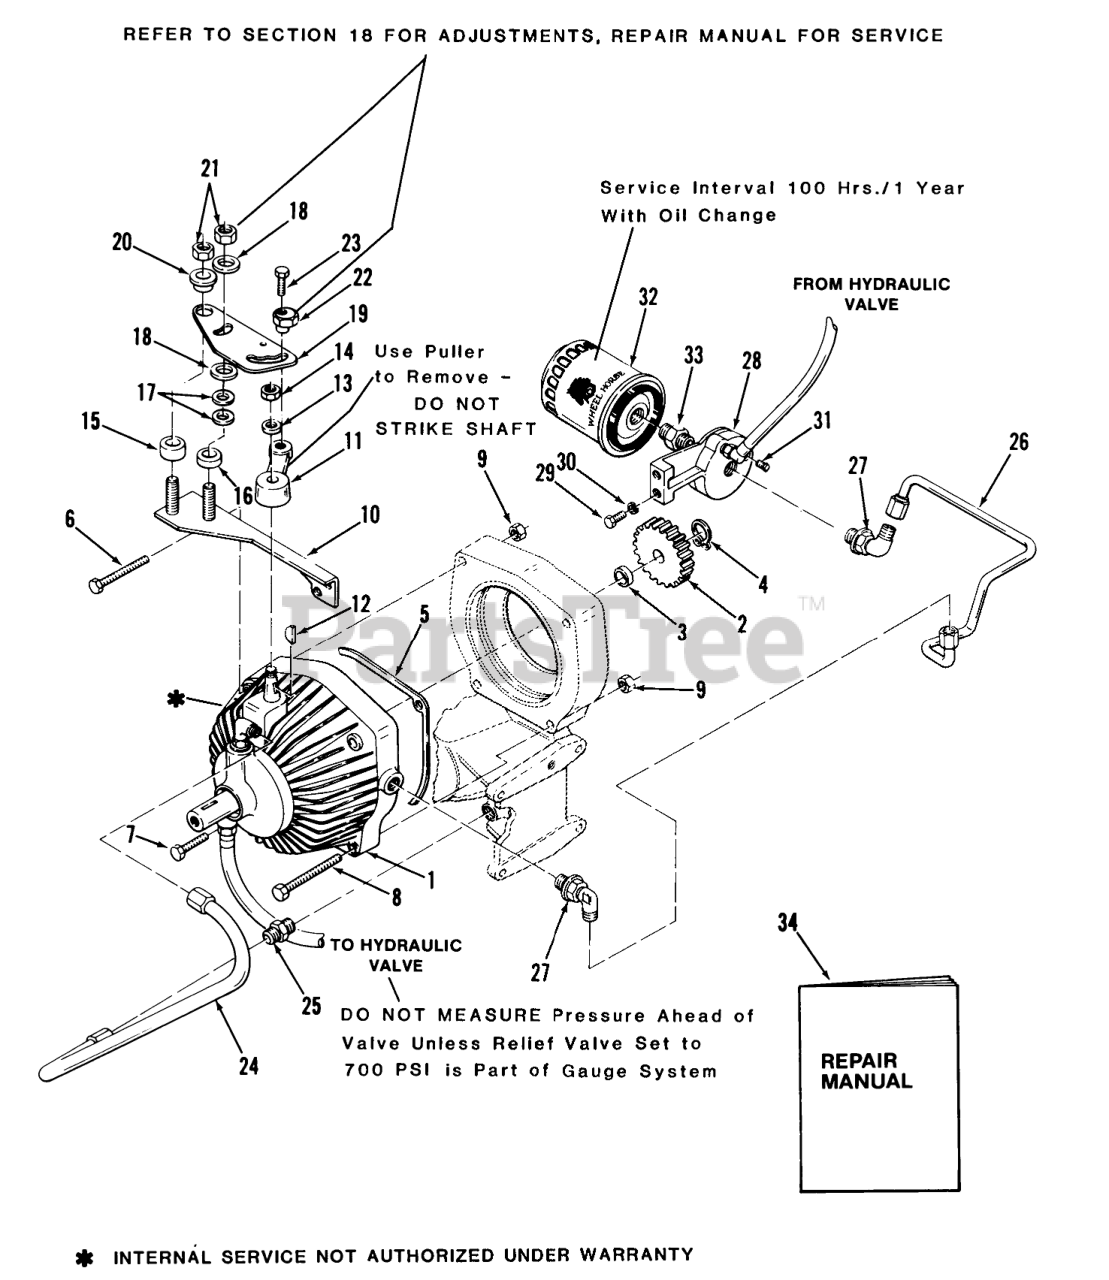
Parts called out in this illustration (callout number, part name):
1	Pump & Motor
2	GEAR 20 TEETH DRIVE
2	GEAR 22T DRIVE
3	SPACER GEAR
4	SNAP RING- 5/8 EXT
5	GASKET
6	Hex Bolt
7	Bolt
8	Bolt 3/8-16 x 6 1/2
9	NUT
10	ASSY-PLATE B
11	ARM-SPEED CONTROLB
12	Key #5 Woodruff
13	Washer
14	Nut
15	SPACER-PIVOT
16	SPACER-FRICTION
17	WASHER-SPRING DISC
18	FRICTION WASHER
19	CAM-SPEED CONTROL (NS)
20	CAM-SPACER
23	Bolt
24	ASSY-TUBE SUCTION
25	FITTING-TUBE
26	ASM-TUBE FILTER OUTL
27	ELBOW
28	BASE-FILTER
29	Bolt
30	Lockwasher
31	PLUG 1/4 PIPE ALLEN
32	Filter-Oil
33	FITTING
34	Repair Manual
